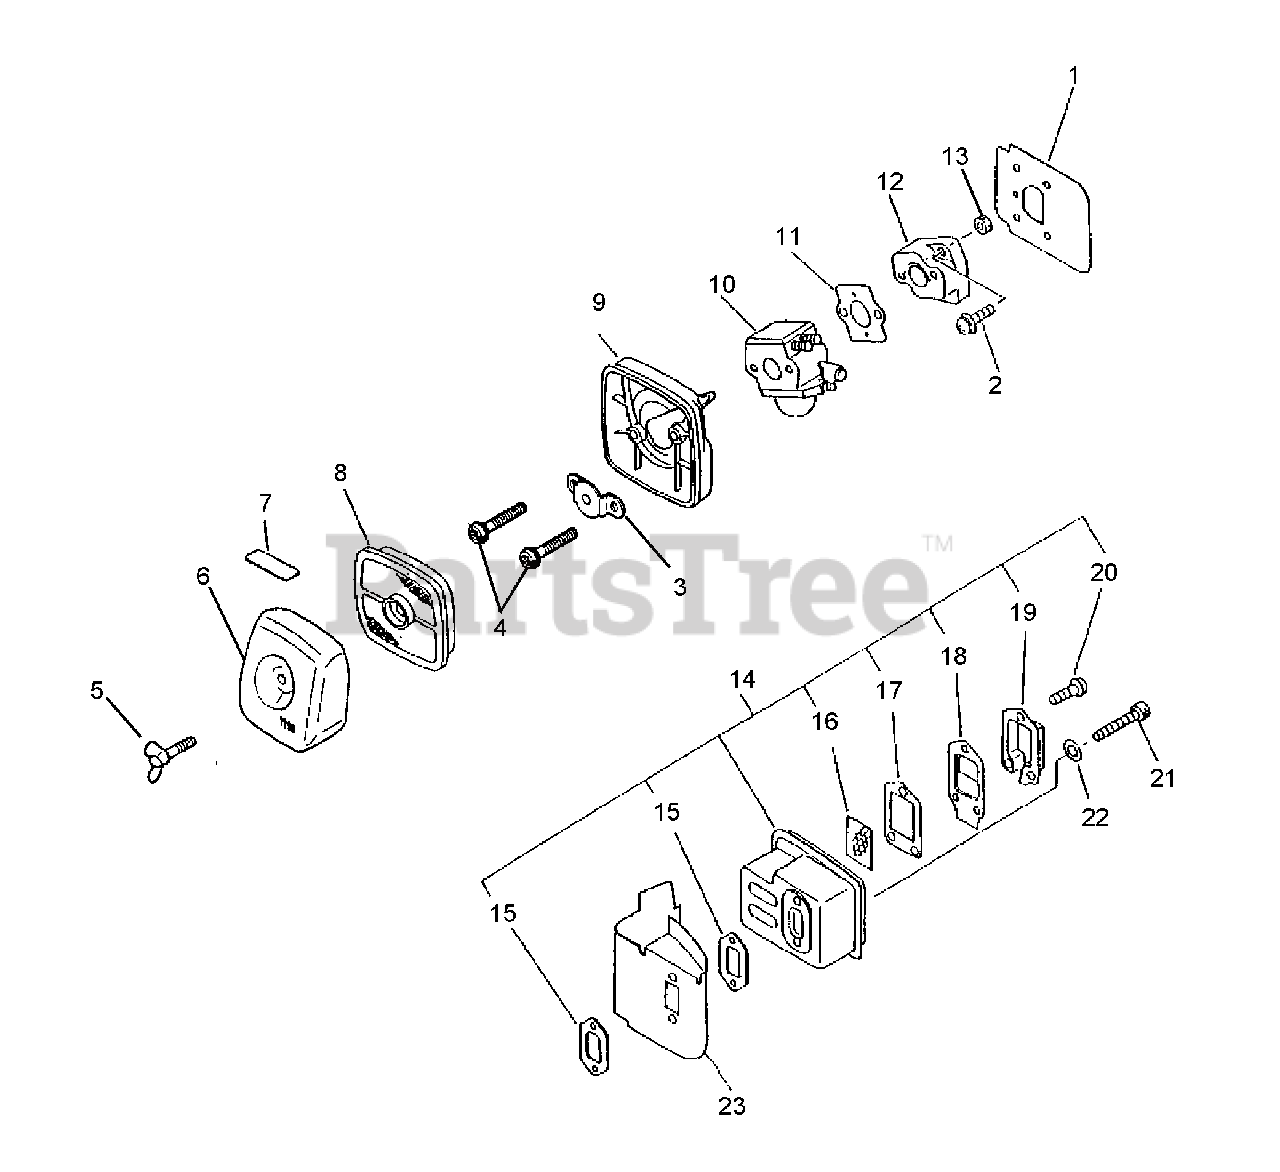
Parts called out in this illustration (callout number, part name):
1	HEAT SHIELD, INTAKE
2	SCREW 5×20
3	PLATE, PREVENT
4	SCREW 5×64
4	SCREW 5×65
5	WINGNUT - 6
5	BOLT, WING 5×20
6	COVER, AIR FILTER
6	COVER, AIR FILTER - GRAY
7	LABEL, CHOKE
8	FILTER, AIR
8	FILTER, AIR - SINGLE LAYER
9	CASE, AIR FILTER
9	AIR FILTER CASE ASSY
10	CARBURETOR - WT -168A
10	CARBURETOR - C1U-K18
10	CARBURETOR - C1U-K35
10	CARBURETOR - C1U-K51
11	GASKET, INTAKE
12	INSULATOR, INTAKE
13	NUT M5
14	MUFFLER ASSY
15	GASKET, EXHAUST
16	SCREEN, SPARK ARRESTER
17	GASKET, EXHAUST
18	GUIDE, EXHAUST
19	GUIDE, EXHAUST
19	GUIDE, EXHAUST - INNER
20	SCREW 4×10
21	BOLT 5×55
22	WASHER, FLAT 5.5×10×0.8
23	HEAT SHIELD, EXHAUST
